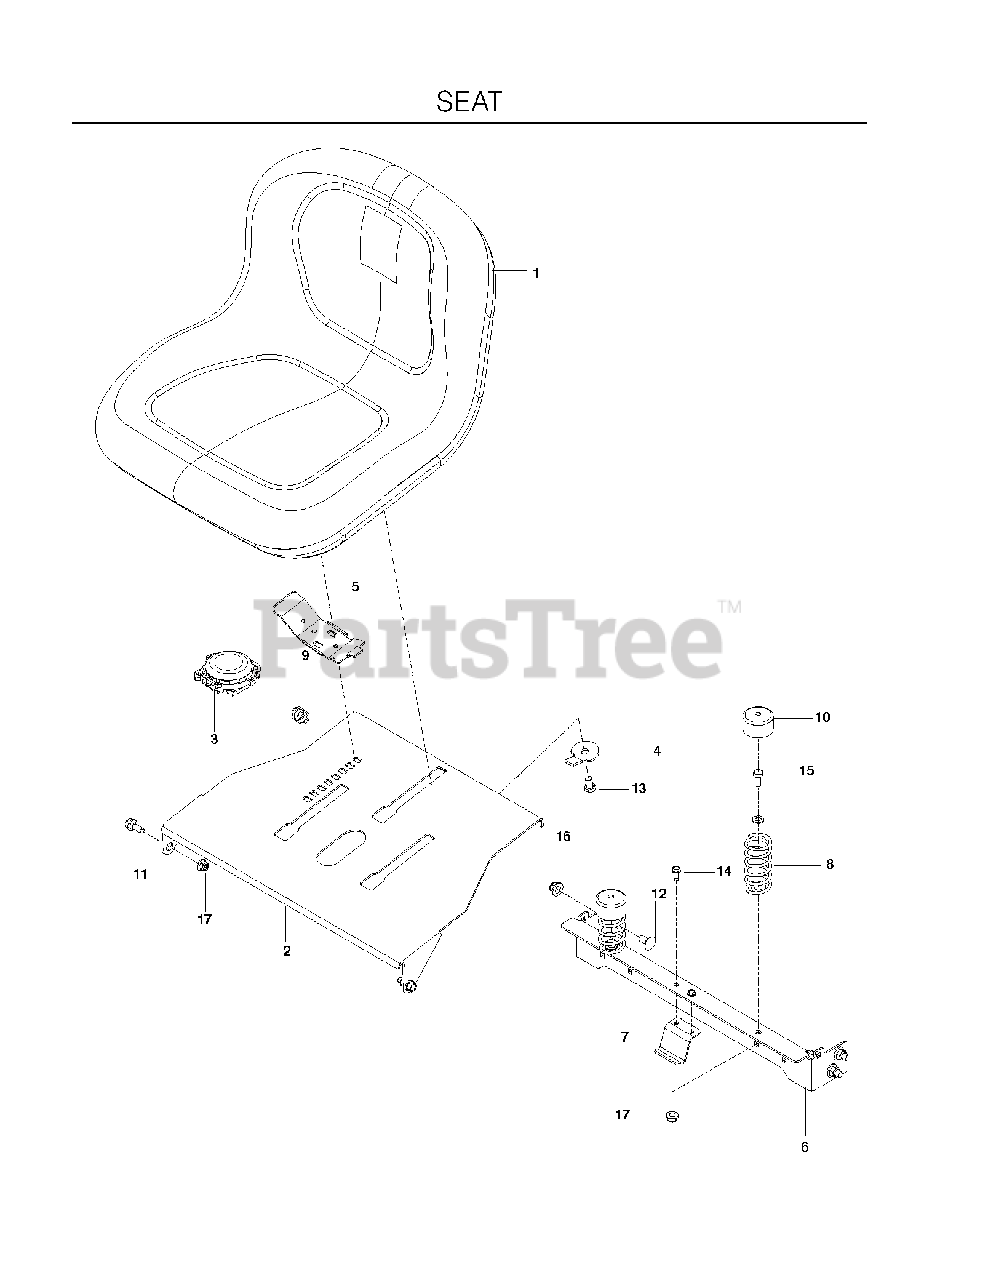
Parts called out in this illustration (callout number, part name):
1	SEAT,BLACK W/ARMREST PROVISION
2	PLATE, SEAT, BLUE
3	SWITCH, SEAT N/C
4	STOP, SEAT, BLACK
5	HANDLE.SLIDE.SEAT.TEX.
6	SEAT SUPPORT, REAR, BLUE
7	HOLDING DEVICE, FUEL TANK, BLK
8	SEAT SPRING
9	SPRING.LATCH.SEAT.TEX
10	SPRING CAP
11	BOLT, SHOULDER
12	RHSNB 3/8-16 X 3/4 GR5 ZD
13	HCS 3/8-16 X 5/8 GR 5 ZD
14	SCREW 1/4 X 5/8
15	HCS 5/16C X 3/4
16	NUT 3/8-16 HEX FLG NYLOC ZD
17	5/16-18 NYLOC FLANGE NUT
